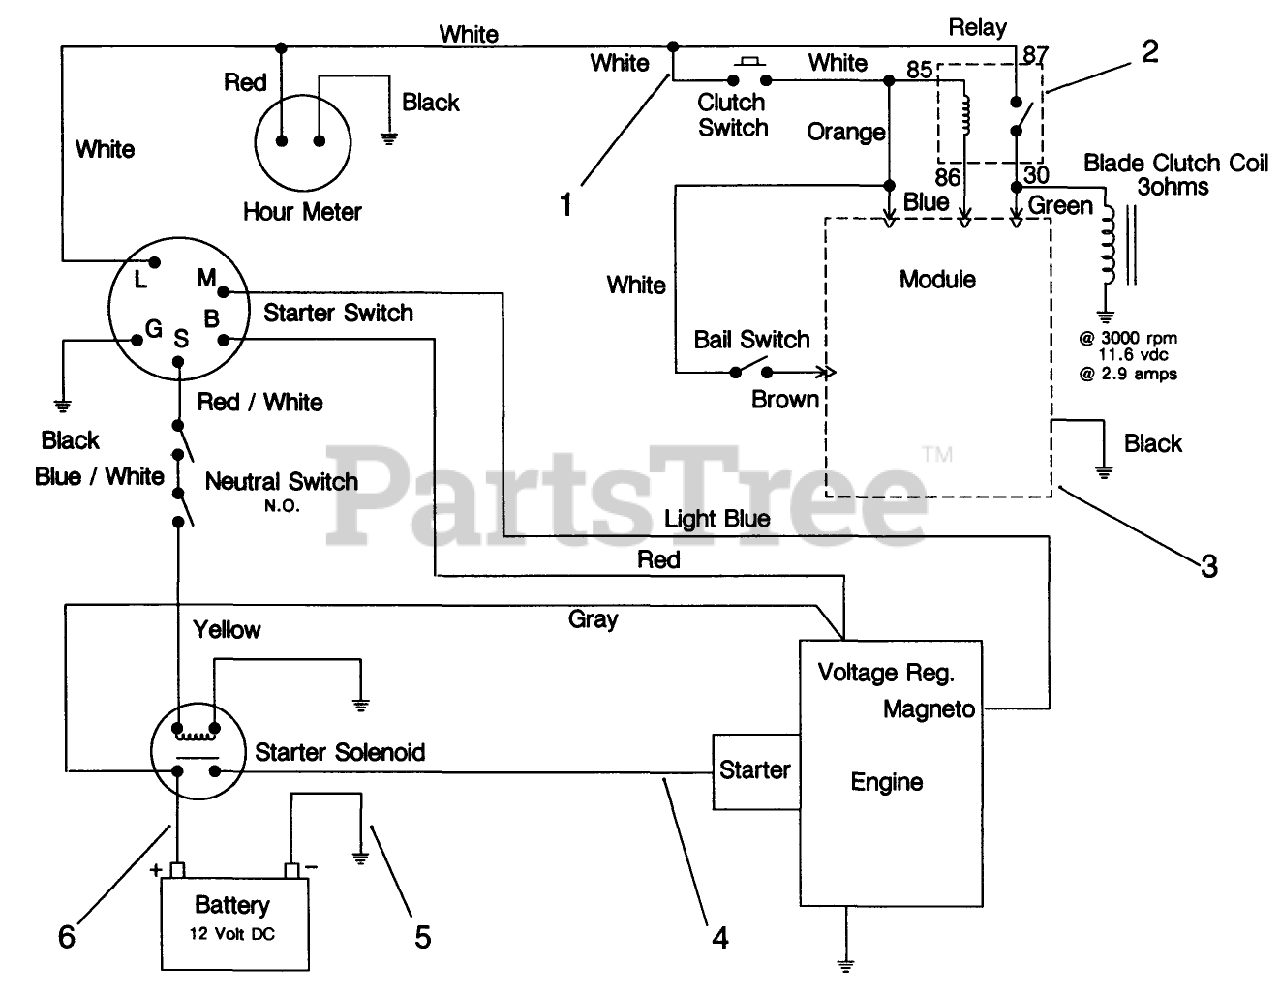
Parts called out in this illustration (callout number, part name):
4	WIRE-SOLENOID/STARTER
5	WIRE ASM
6	WIRE ASM
